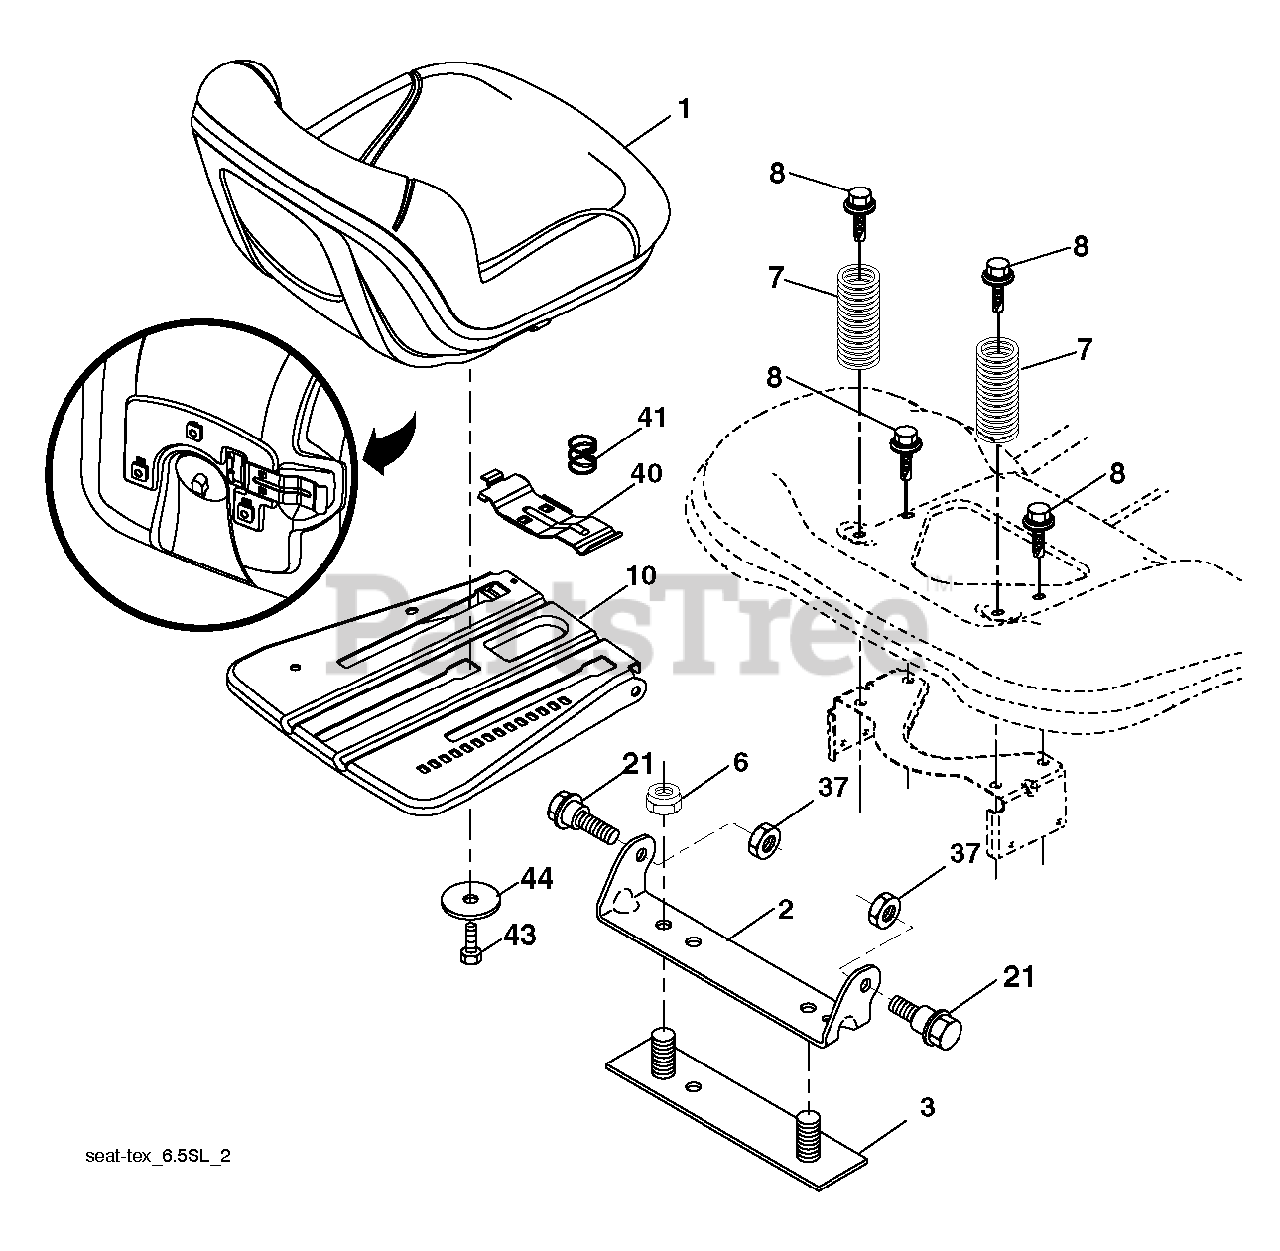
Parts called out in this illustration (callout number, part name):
1	SEAT.TH151.GREY.PREM.HUSQ.MI
2	BRKT.PIVOT.FENDER
3	STRAP
6	NUT
7	SPRING COMPRESSION
8	BOLT, 5/16-18 X 1 3/4
10	PAN.ASM.SEAT.3PT
21	BOLT.SHOULDER.5/16-18
37	NUT.71038.31-18.HEX.NYLOCK
40	HANDLE.SLIDE.SEAT.TEX.BLACK
41	SPRING.LATCH.SEAT.TEX
44	WASHER 13/32 X 2-3/8 X 12GA
